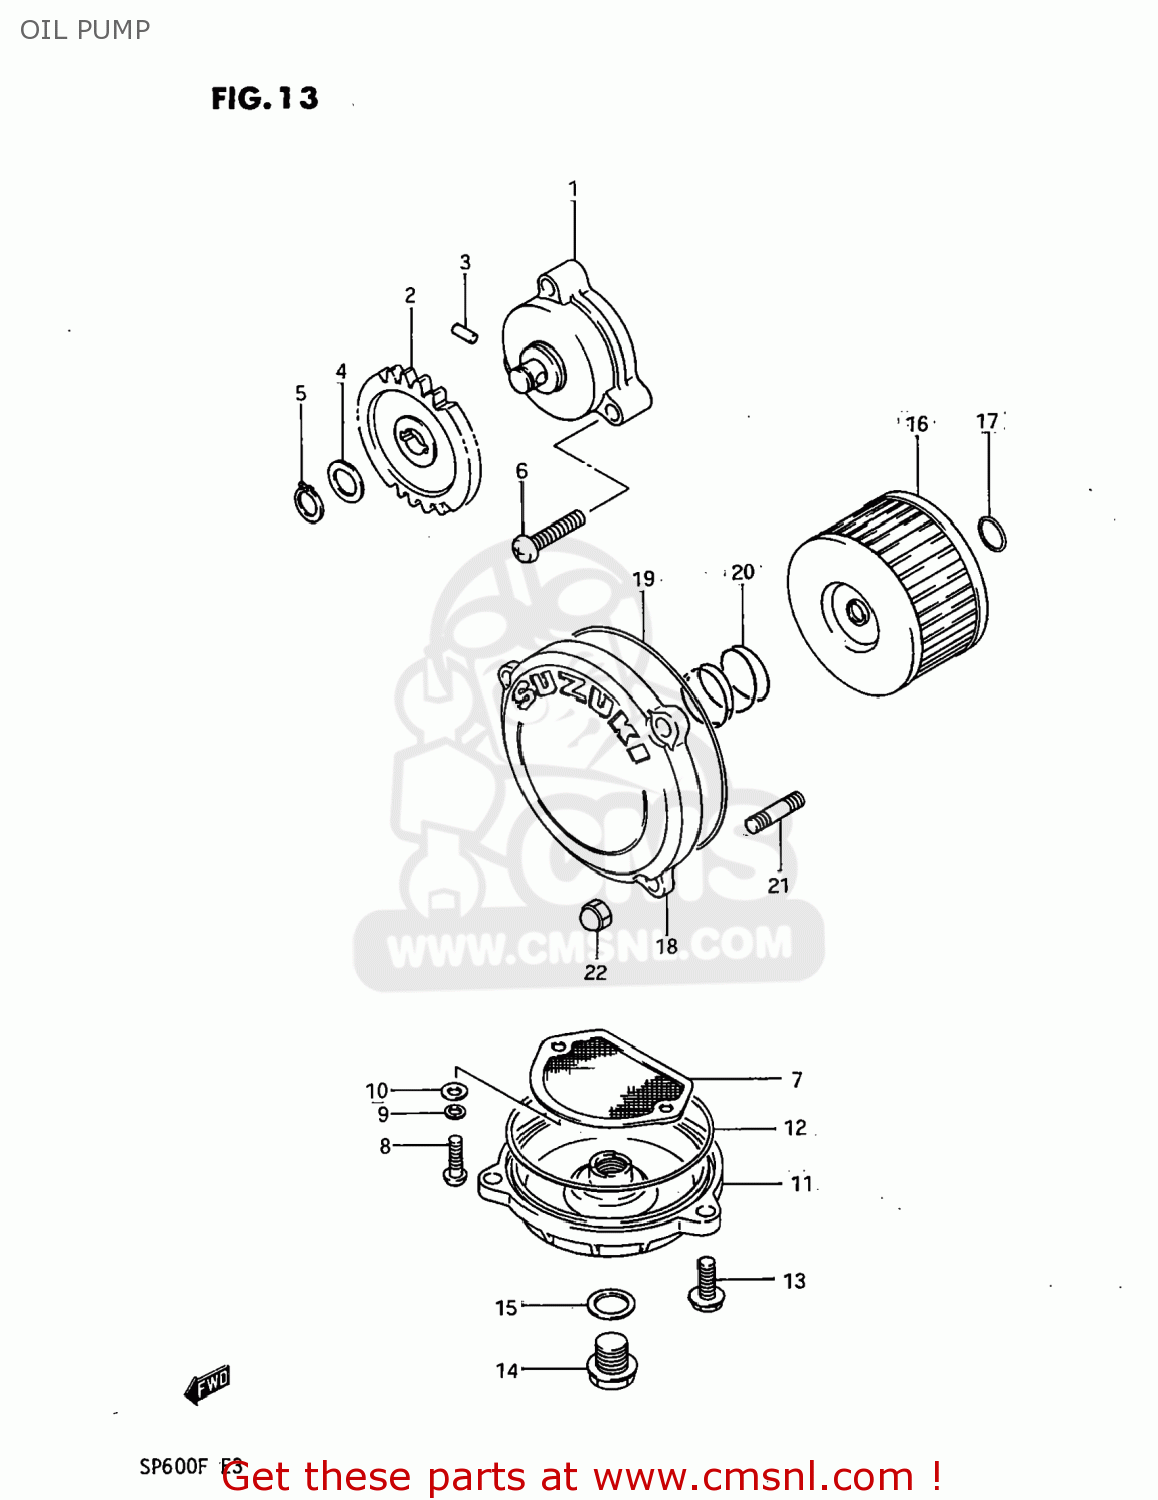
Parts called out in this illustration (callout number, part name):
1	PUMP ASSY,ENGINE OIL
2	GEAR,OIL PUMP DRIVEN
3	PIN(4X15.8)
4	SHIM
5	CIRCLIP
6	SCREW
7	STRAINER,ENGINE OIL
8	SCREW 5X12
9	LOCK WASHER
10	WASHER
11	CAP,OIL STRAINER
12	O RING(D:2.4,ID:85)
13	BOLT,REAR
14	PLUG
15	GASKET(14X19.2X2) (NAS)
16	FILTER,ENGINE OIL
17	O RING(D:2.4,ID:15.8)
18	CAP,OIL FILTER
19	O RING(D:2.4,ID:73)
20	SPRING
21	STUD 6X12
22	NUT 6MM
